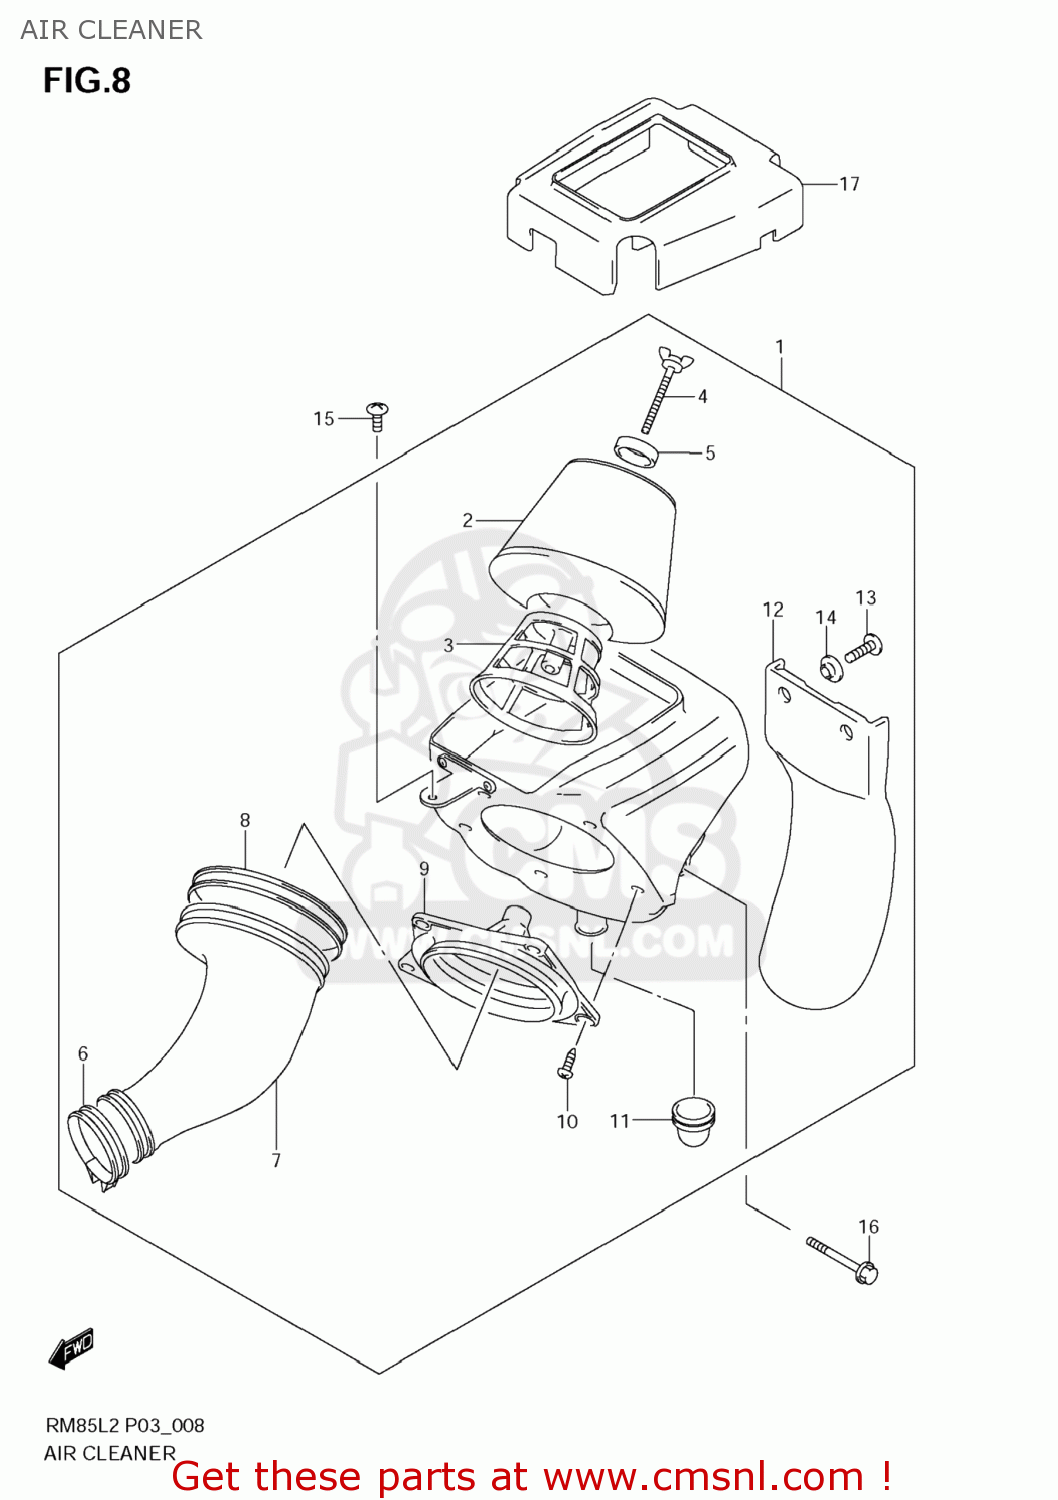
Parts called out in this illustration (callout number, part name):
1	CLEANER ASSY,AIR
2	FILTER ASSY
3	HOLDER
4	BOLT,WING
5	WASHER,AIR CLEANER
6	CLAMP
7	TUBE,OUTLET
8	CLAMP
9	BASE,FILTER
10	SCREW
11	HOSE,AIR CLEANER DRAIN
12	GUARD,MUD
13	SCREW
14	COLLAR
15	SCREW
16	BOLT(6X45)
17	MUDGUARD,B
